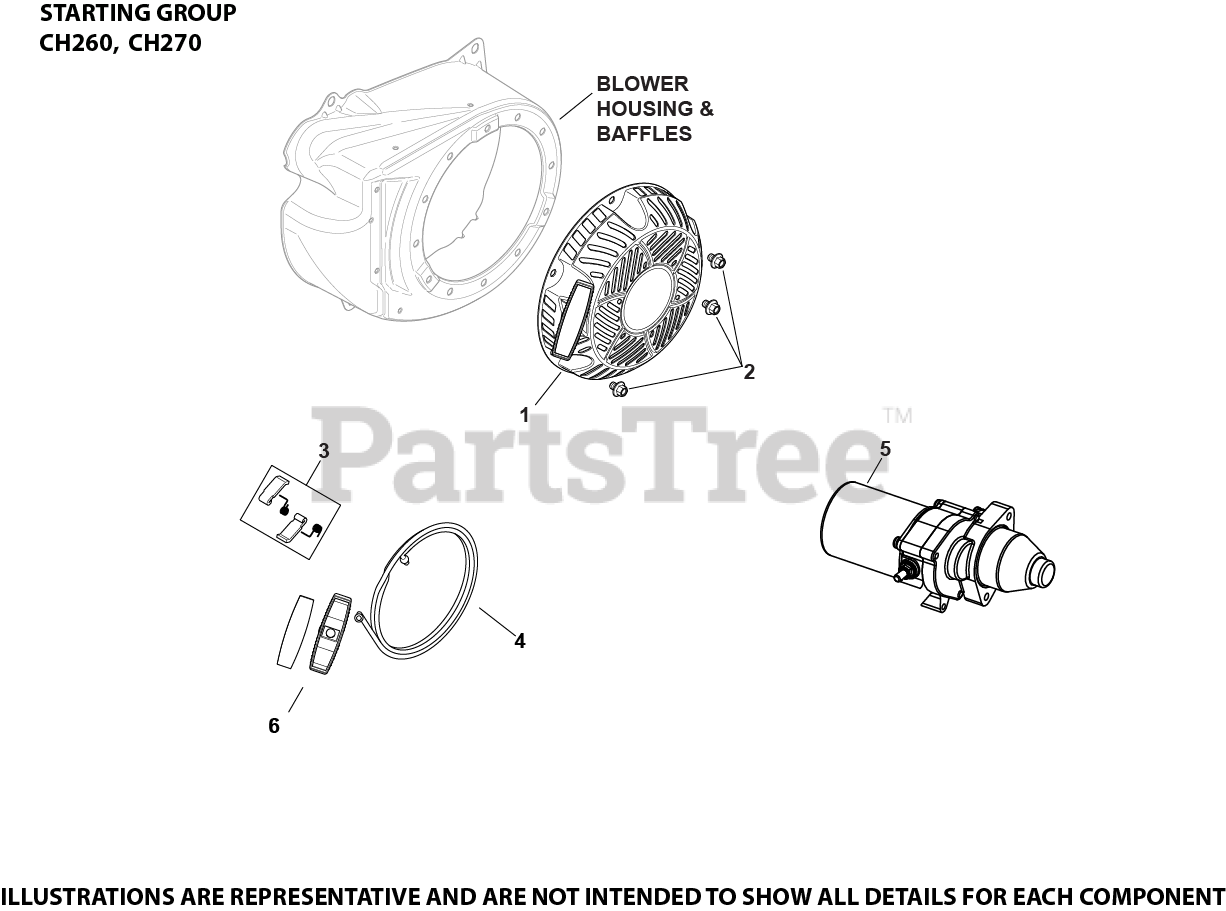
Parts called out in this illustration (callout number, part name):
1	RETRACTABLE STARTER ASSEMBLY
2	SCREW, M6 X 8 HEX FLANGE HEAD (CKY)
3	KIT, PAWL REPAIR
4	ROPE, STARTING
6	KIT, STARTER ROPE W/HANDLE
